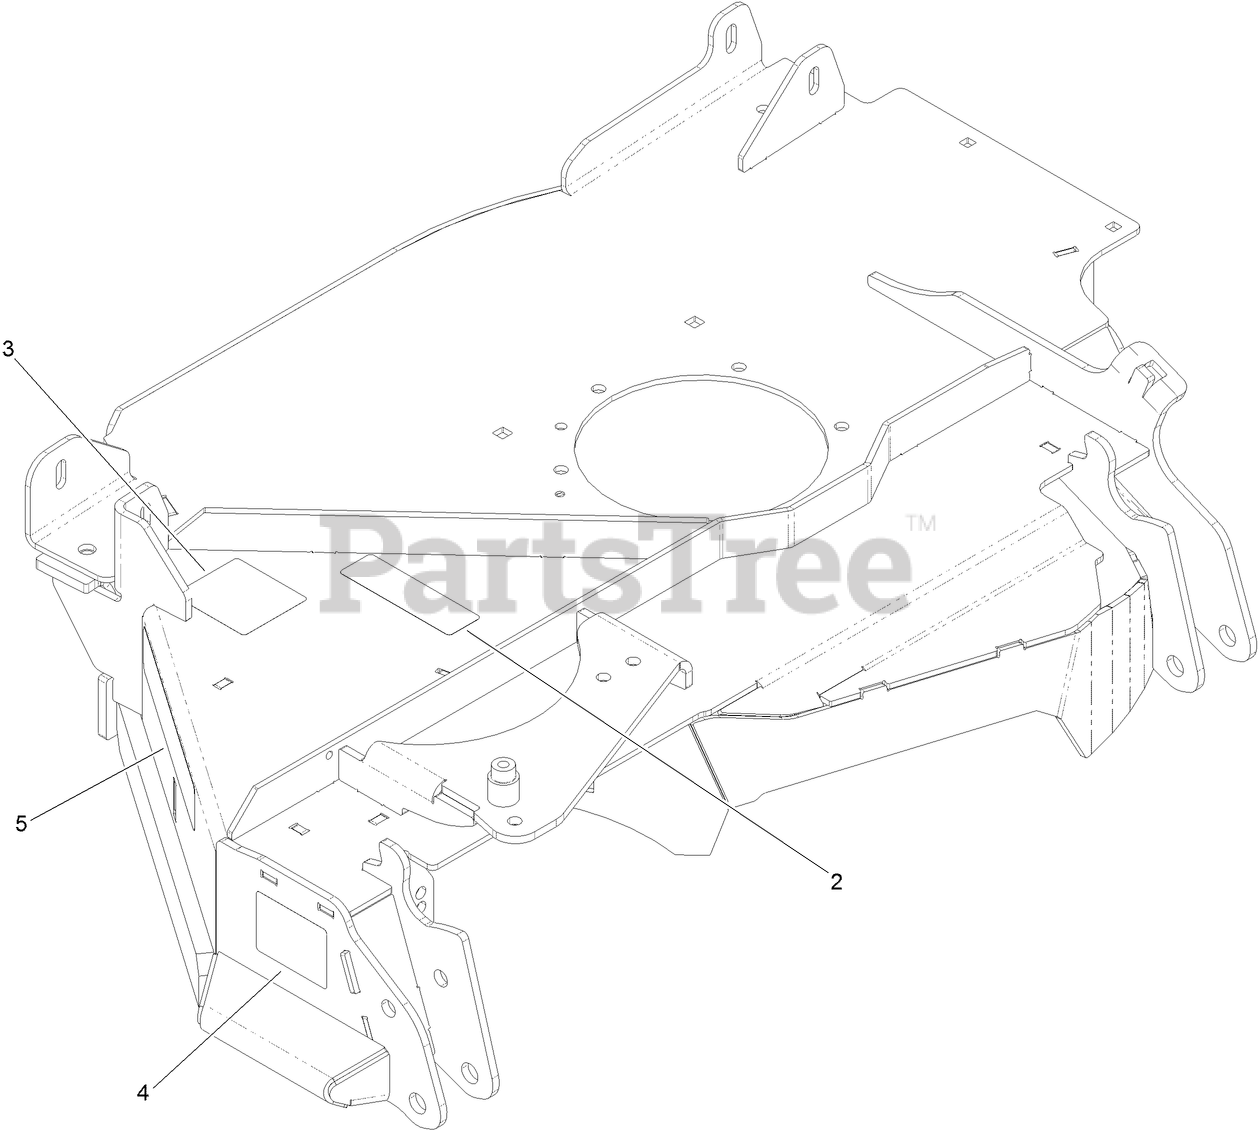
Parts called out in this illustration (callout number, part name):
2	DECAL-NO STEP
3	DECAL-SCRATCH COVER
5	RIVET-POP
